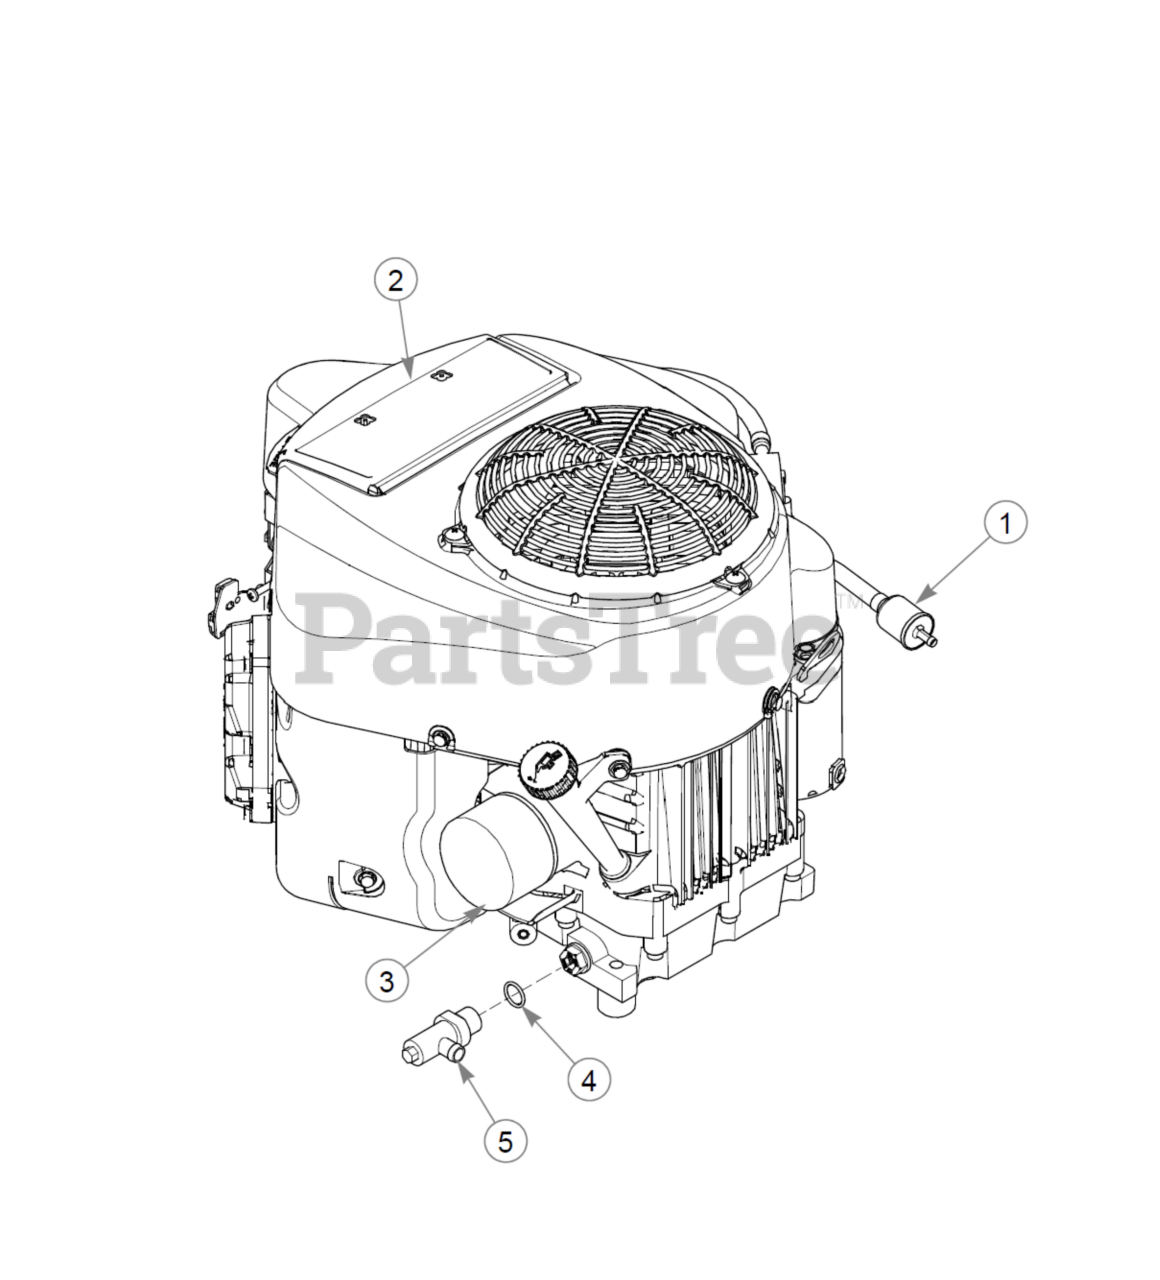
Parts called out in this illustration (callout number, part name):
1	FUEL FILTER - IN LINE
2	AIR FILTER - MAIN
3	ENGINE OIL FILTER
5	VALVE, OIL DRAIN
